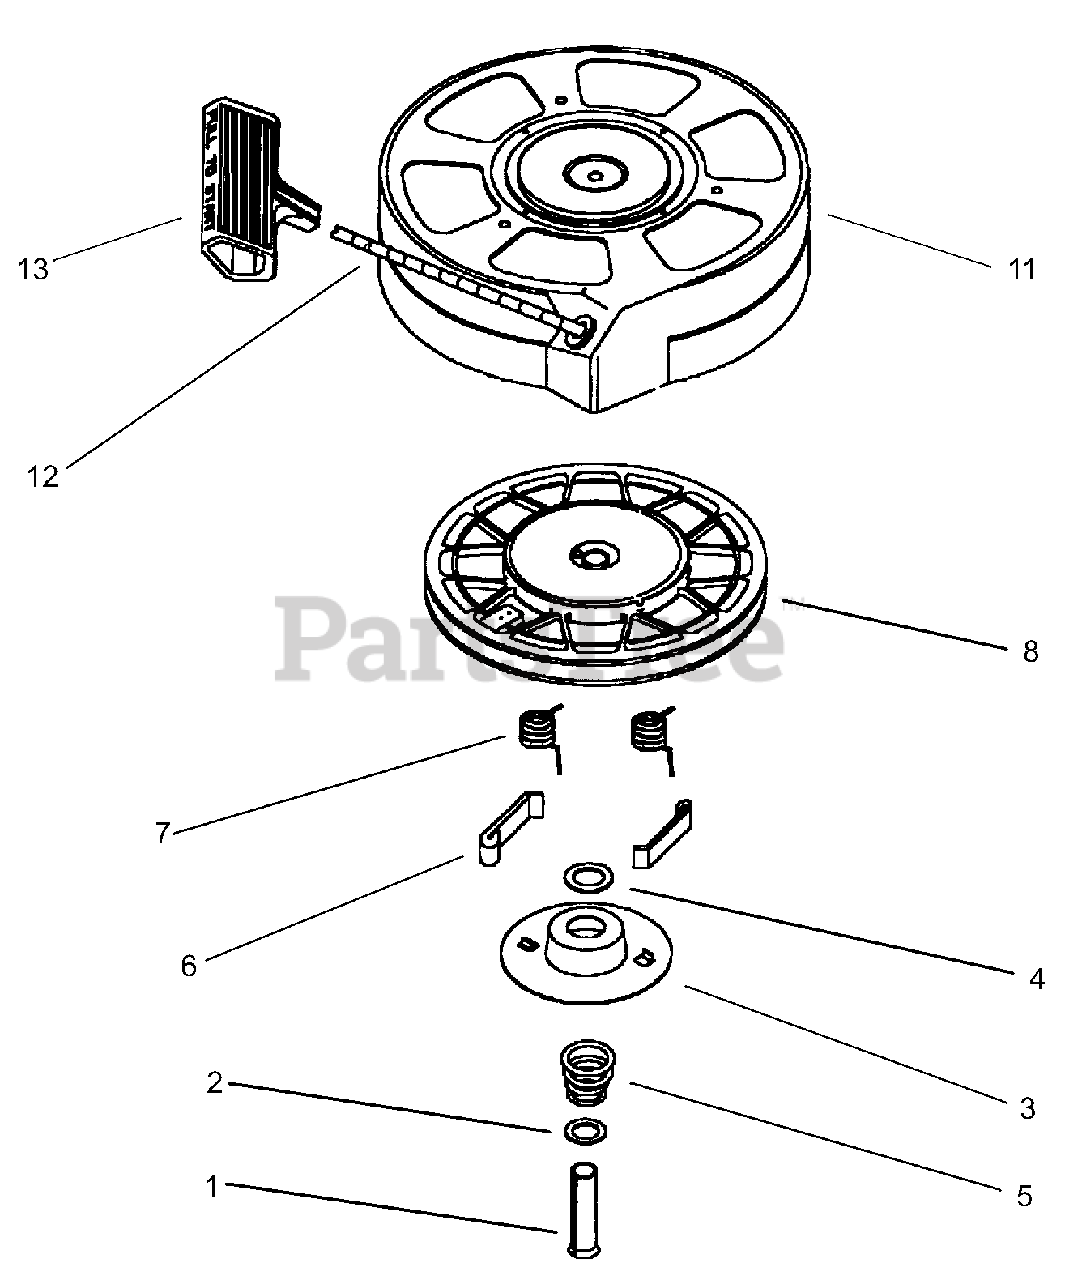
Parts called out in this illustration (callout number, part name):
1	Spring Pin (Incl. 4)
2	Washer
3	Retainer
4	Washer
5	Brake Spring
6	Starter Dog
7	Dog Spring
8	Pulley & Rewind Spring Ass'y.
11	Starter Housing Ass'y. (40 degree grommet)
12	Starter Rope (98" X 9/64" dia.)
13	Starter Handle
